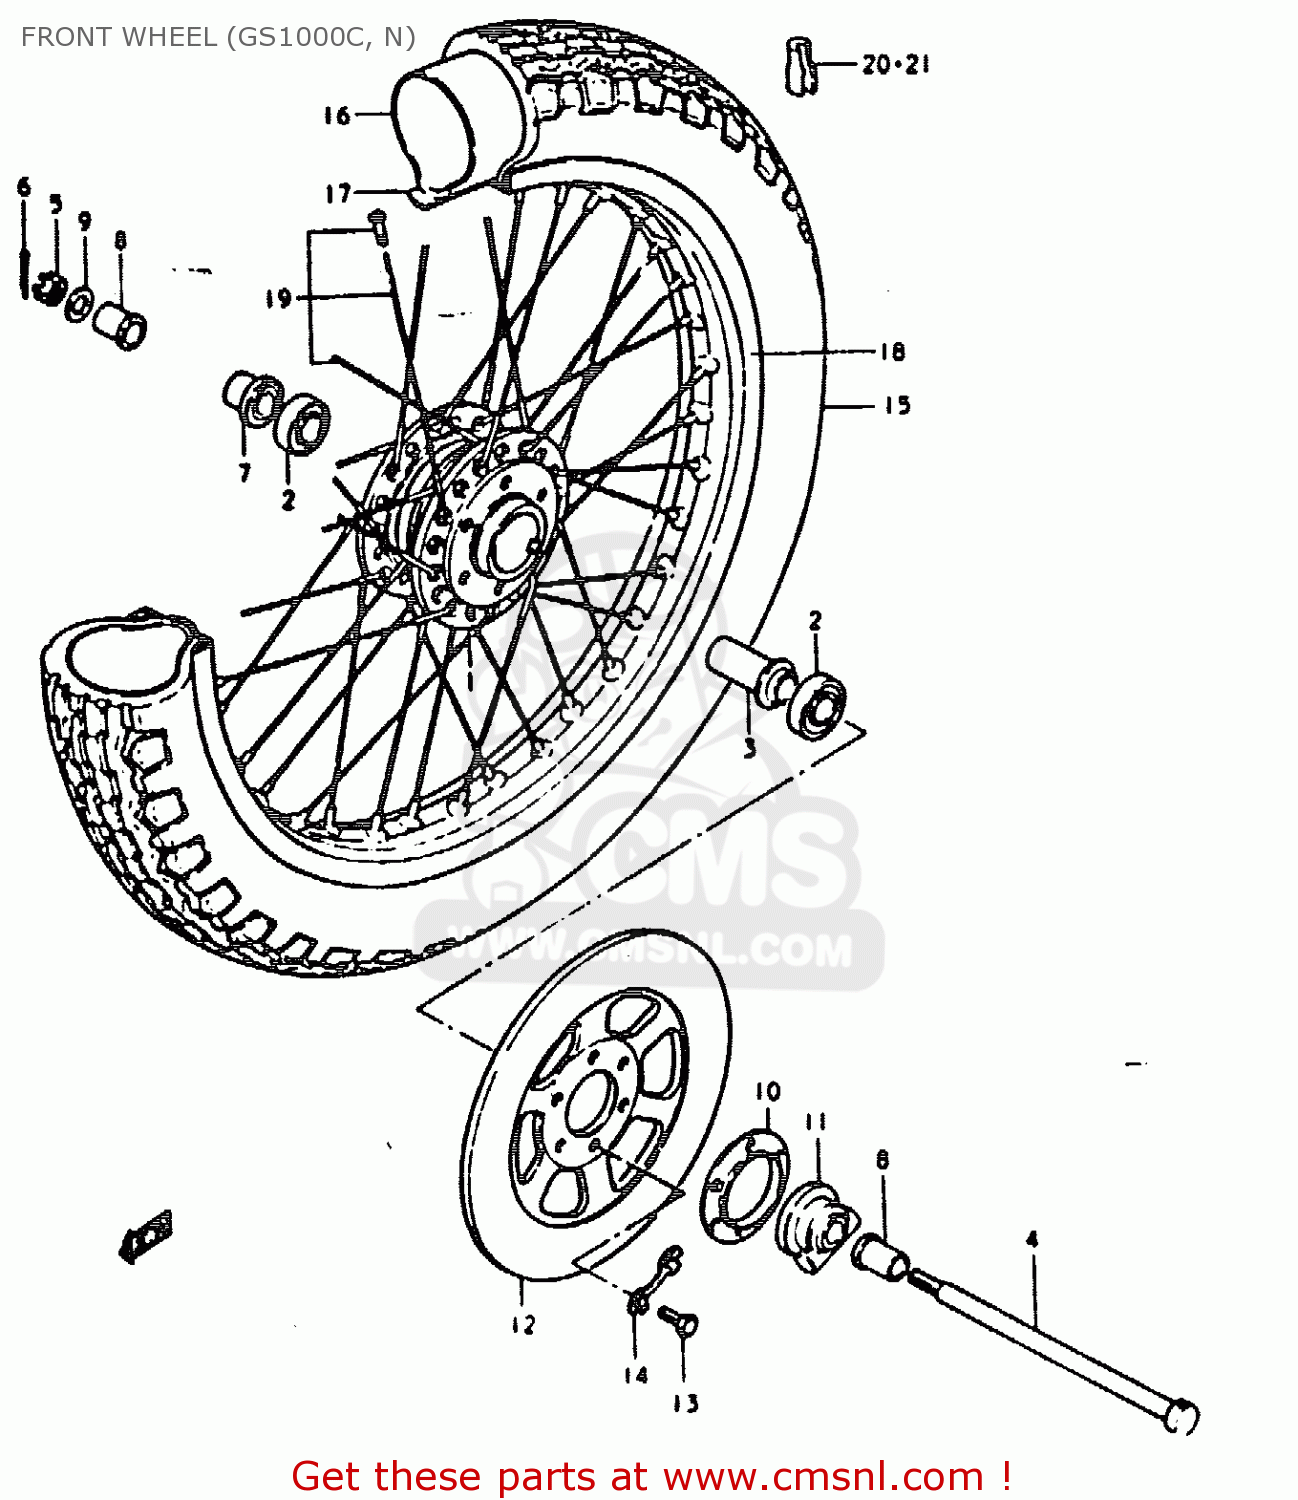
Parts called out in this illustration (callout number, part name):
1	DRUM,FRONT HUB
2	BEARING
3	SPACER,FR HUB BEARING
4	AXLE,FR
5	NUT 12MM
6	COTTER PIN
7	SPACER,FR AXLE,R
8	SPACER,FR AXLE,L
9	WASHER
10	DUST SEAL
11	BOX ASSEMBLY,SPEEDOMETER GEAR
12	DISC,BRAKE
13	BOLT(8X30)
14	WASHER
15	TIRE,FRONT
16	TUBE,INNER
17	PROTECTOR,WHL INR TUBE
18	RIM,FRONT WHEEL
19	SPOKE SET,FRONT
20	BALANCER,WHEEL (B)
21	BALANCER,WHEEL (30G)
